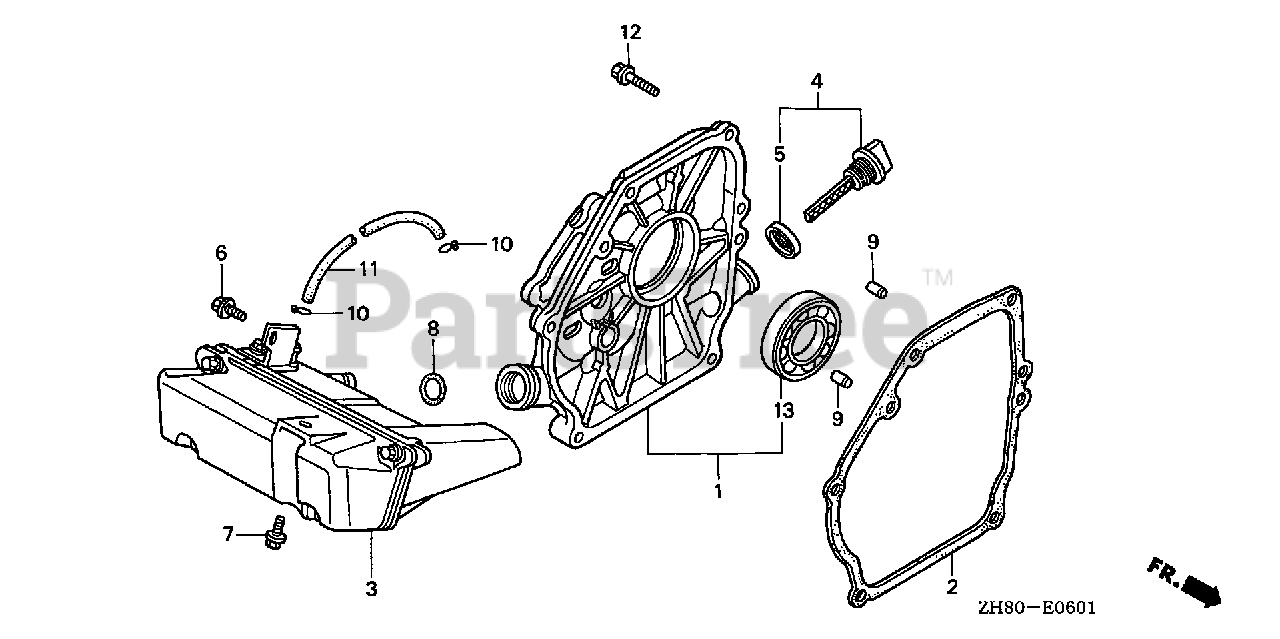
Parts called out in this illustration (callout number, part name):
1	COVER ASSY., CRANKCASE
2	GASKET, CASE COVER
3	TANK ASSY., OIL
4	CAP ASSY., OIL FILLER (GRAY)
5	GASKET, OIL FILLER CAP
6	BOLT, FLANGE (6X14) (CT200)
7	BOLT, FLANGE (6X16) (CT200)
8	O-RING (15.8X2.4) (SHOWA)
9	PIN, DOWEL (8X14)
10	CLIP, TUBE (B7)
11	BULK HOSE, VACUUM (3.5X8000) (3.5X130)
12	BOLT, FLANGE (8X32)
13	BEARING, RADIAL BALL (6205)
